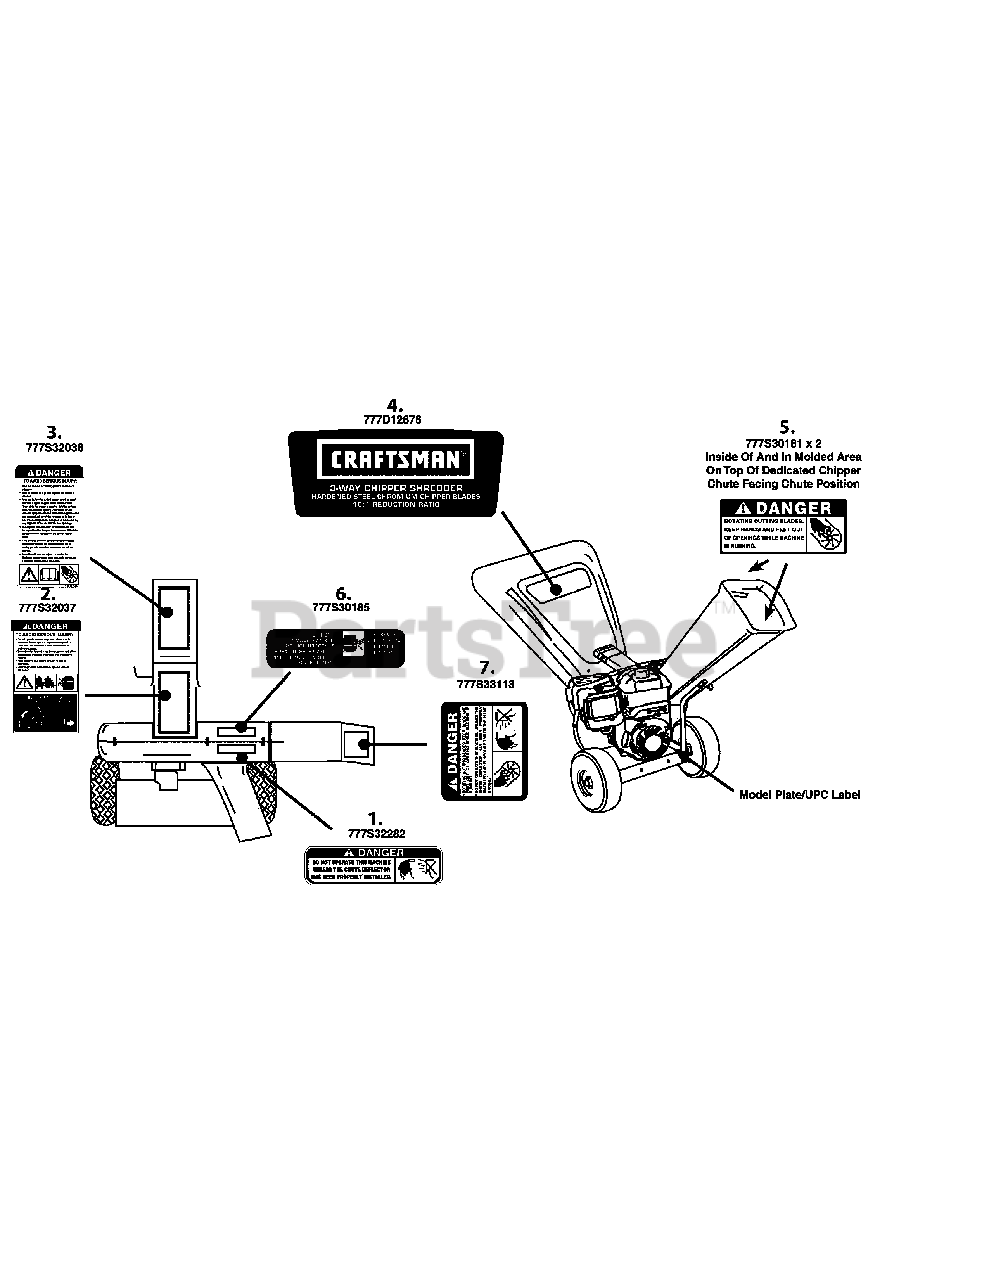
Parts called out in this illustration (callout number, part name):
1	LABEL-DANGER CHIPP
2	LABEL-DANGER CHIPP
3	LABEL CHP/SHRD
4	LABEL-CS:CRAFTSMAN:CHRM BLDS
5	LABEL-TOP CHUTE DANGER
6	LABEL-CHIPPER SHREDDER CHUTE
7	LABEL-CHUTE
